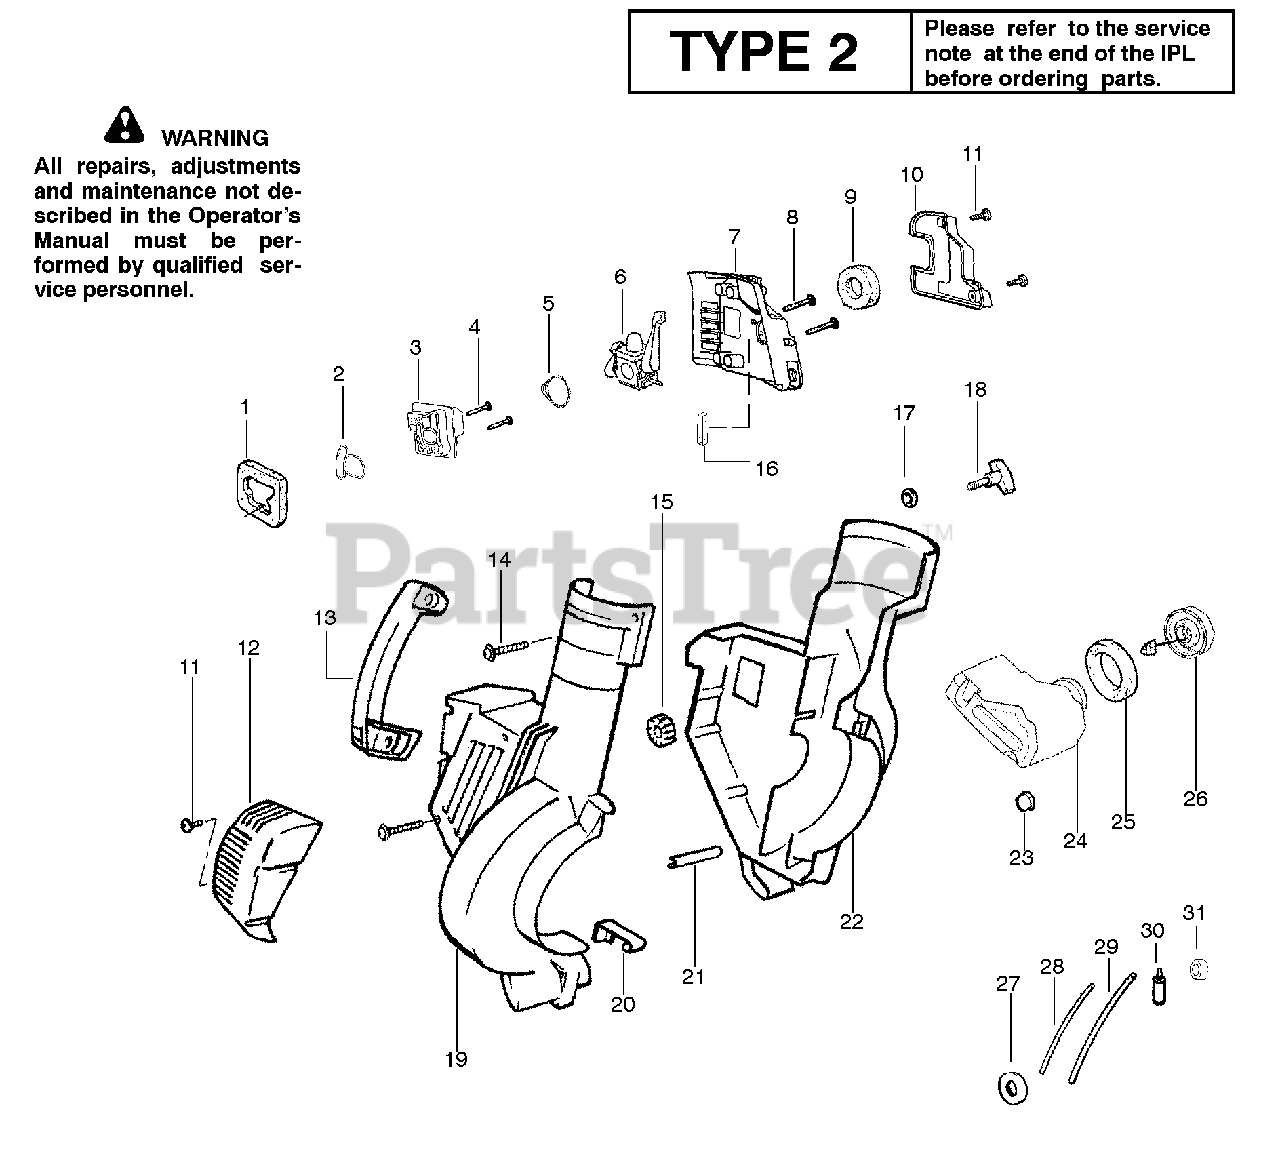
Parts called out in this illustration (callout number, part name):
1	Air Dam (kit)
2	Gasket-Adapter (kit)
3	Carburetor Adaptor
5	Gasket-Carburetor (kit)
6	Kit-Carb Ass'y. (C1Q-W11)
6	Kit-Carb Ass'y. (C1Q-W11C)
6	Kit-Carb Ass'y. (WT-606)
8	Screw-Carb.
9	Filter-Air
10	Cover-Air Filter
12	Guard-Muffler
15	Isolator
16	Foam 25.4mm (kit)
18	Knob-Blower
19	Housing-Right
20	Spring-Cover Latch
21	Guide-Starter Rope
22	Housing-Left
23	Isolator-Crankcase
24	Assy-Fuel Tank
25	Gasket-Fuel Tank
26	Fuel Cap w/Retainer
27	Grommet-Shroud
28	Kit-Line Carb/Purge
29	Kit-Line Tank/Purge
30	Assy-Fuel Pick-up
31	Grommet-Fuel line (kit)
